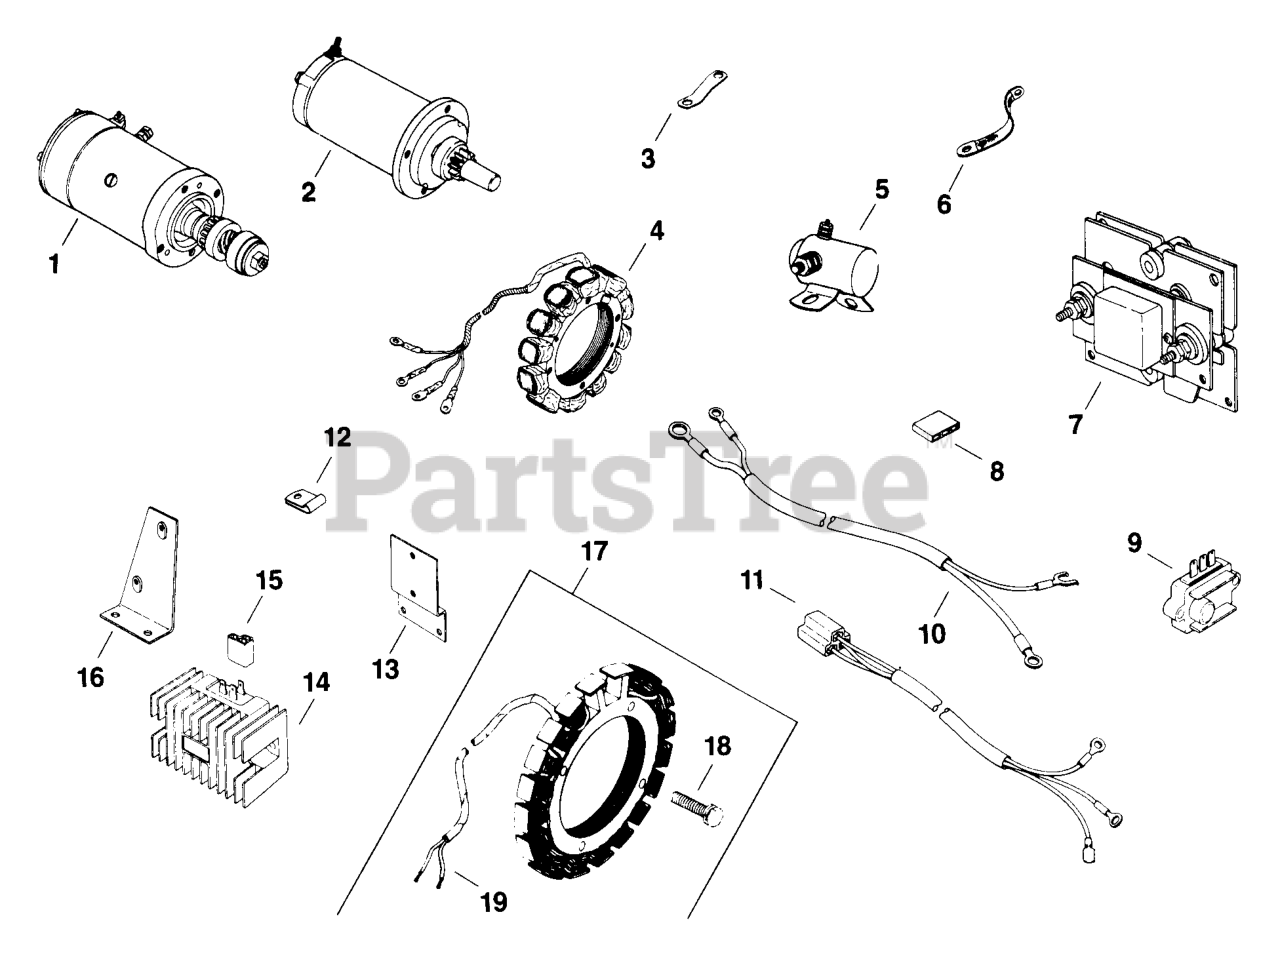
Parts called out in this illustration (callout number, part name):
1	KIT, STARTER - DISCONTINUED
2	STARTER - USE 48 098 04
5	RELAY - USE 48 404 02
14	REGULATOR - USE 41 403 06
15	CONNECTOR - DISCONTINUED
17	KIT, 15 / 20 AMP STATOR
18	SCREW, WSH HD TAP #10-24X3/4" USE 25 086 97-S
A-277214-S	KIT, STARTER - DISCONTINUED
